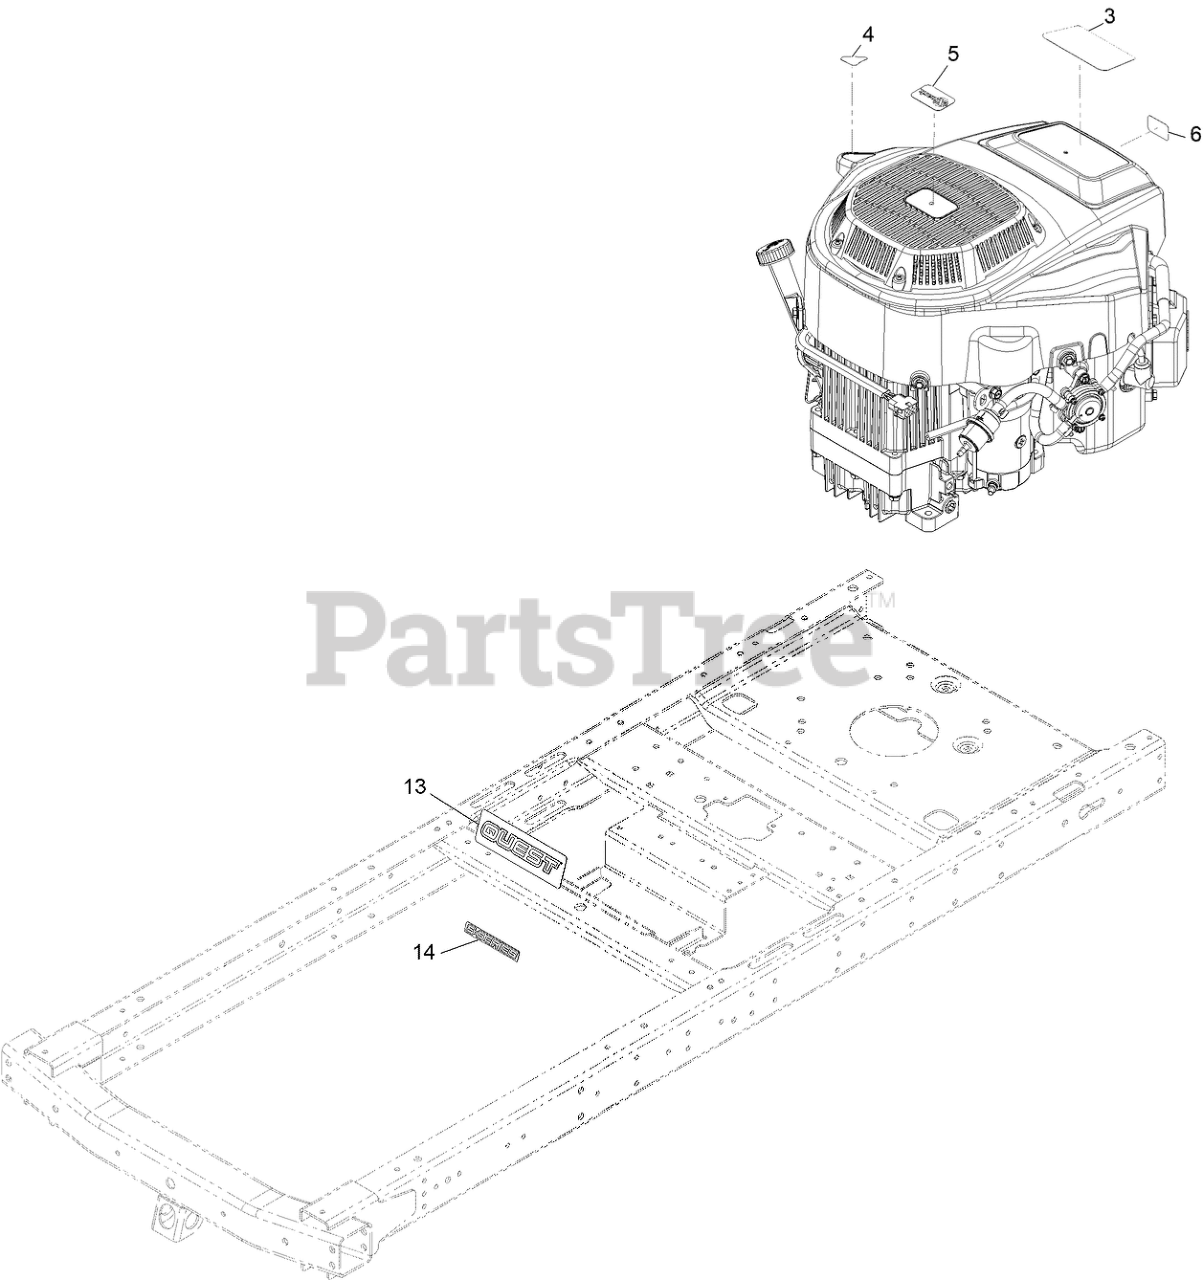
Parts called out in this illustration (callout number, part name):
3	DECAL-ENGINE 708 V-TWIN EXMARK
4	DECAL-DRAIN, OIL
6	PLACARD-INTAKE, EXMARK
13	DECAL-QUEST LOGO
14	DECAL-S-SERIES
